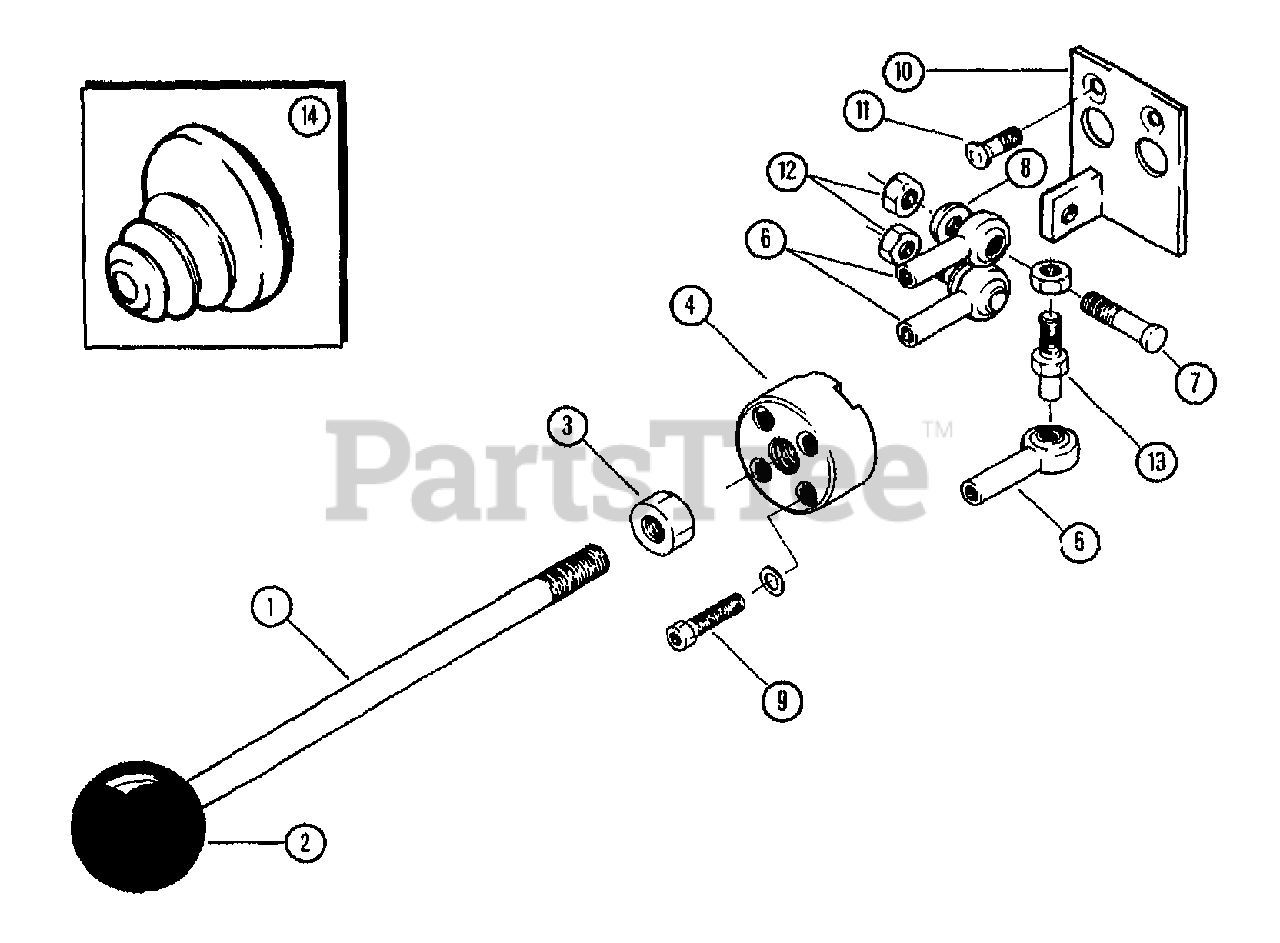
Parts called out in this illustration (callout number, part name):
4	ADAPTOR-HANDLE
6	ROD-END
9	SCR-CAP
10	ASSM-ADAPTOR
11	SCR-CAP
